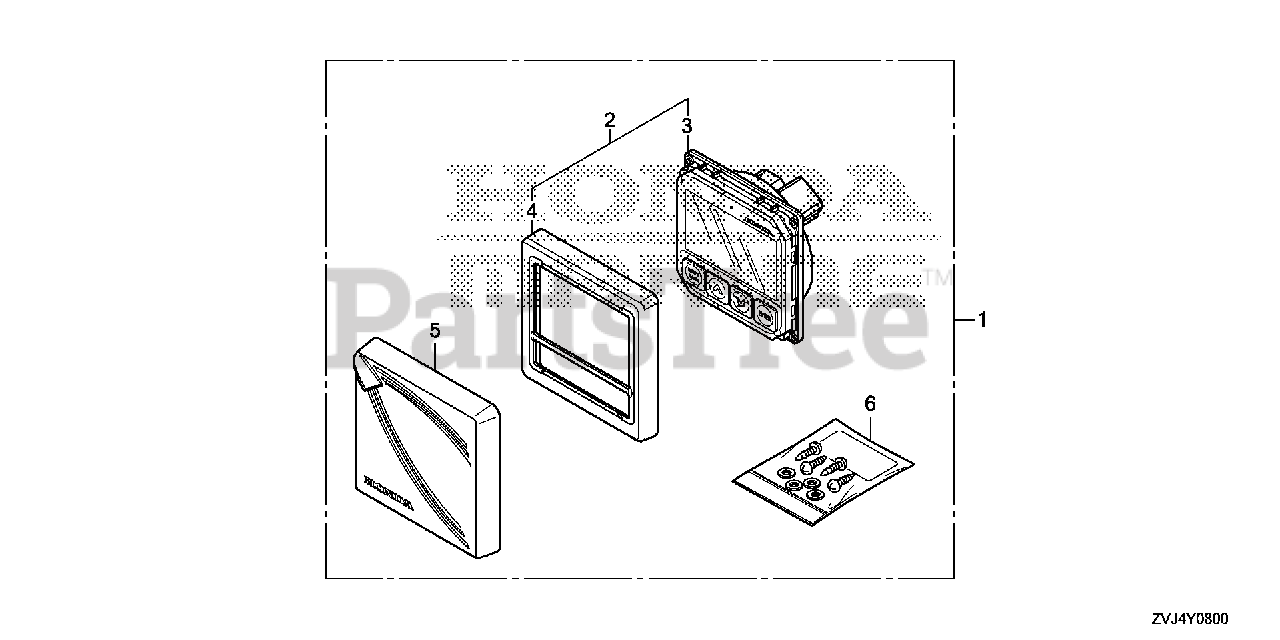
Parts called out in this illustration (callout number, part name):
1	DISPLAY KIT
2	DISPLAY ASSY.
3	DISPLAY UNIT
4	BEZEL, DISPLAY
5	COVER, DISPLAY
6	SCREW SET
